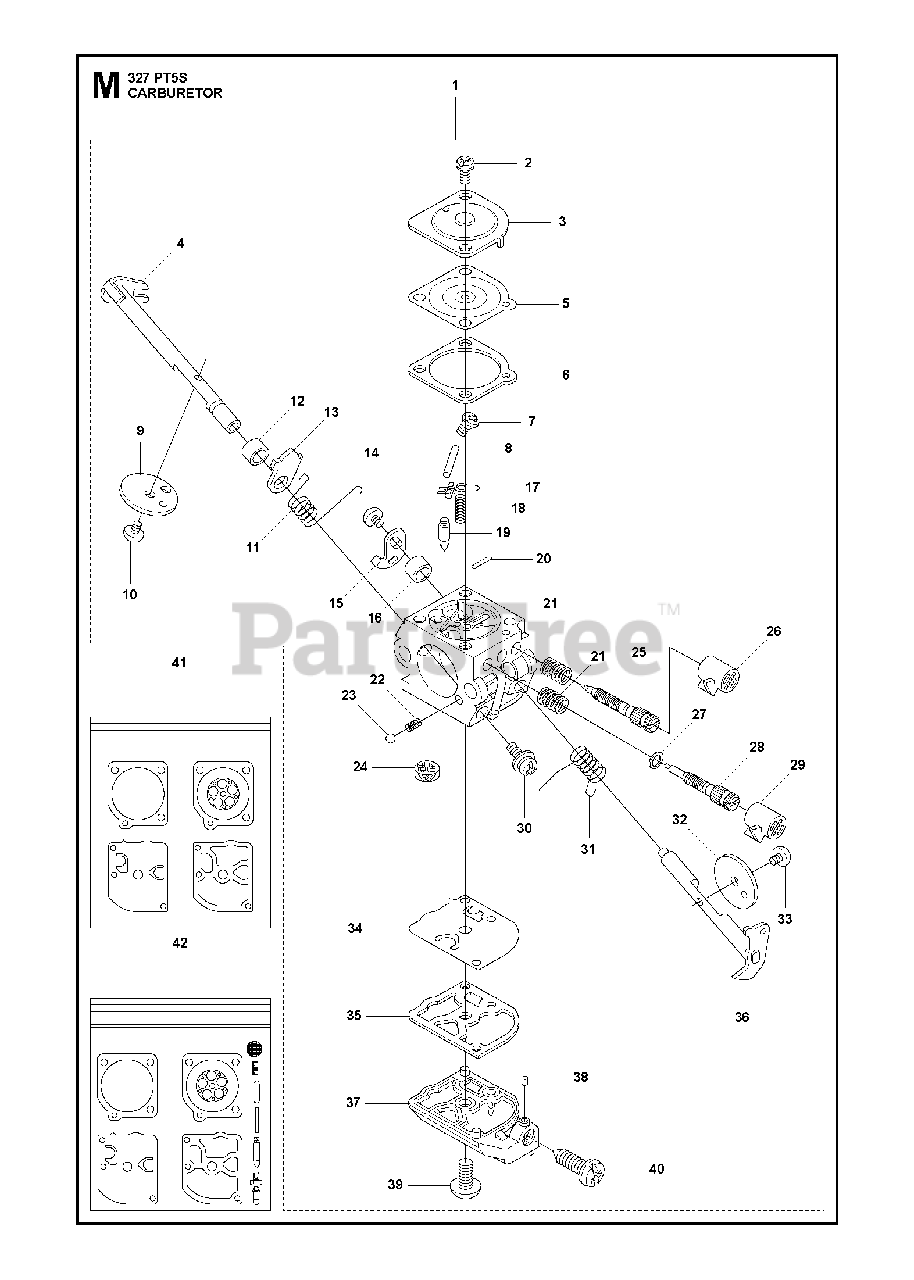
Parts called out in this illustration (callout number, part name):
1	CARBURETOR
2	SCREW
3	COVER
4	CHOKE SHAFT
5	DIAPHRAGM
6	GASKET
7	SCREW
8	PIN FULCRUM
9	CHOKE CAP
10	SCREW
11	SPRING
12	BUSHING
13	LEVER
14	SCREW
15	LEVER
16	SPACER
17	LEVER
18	SPRING
19	INLET NEEDLE
20	PIN
21	SPRING
22	SPRING
23	BALL
24	STRAINER
25	LOW SPEED NEEDLE
26	CAP
27	WASHER
28	NEEDLE HIGH SPEED
29	CAP
30	SCREW *
31	SPRING THROTTLE
32	THROTTLE FLAP
33	SCREW
34	PUMP DIAPHRAGM
35	GASKET
36	SHAFT
37	COVER
38	PLUG
39	SCREW
40	SCREW
41	GASKET KIT (ZAMA GND39)
42	CARBURETOR KIT (ZAMA RB69)
